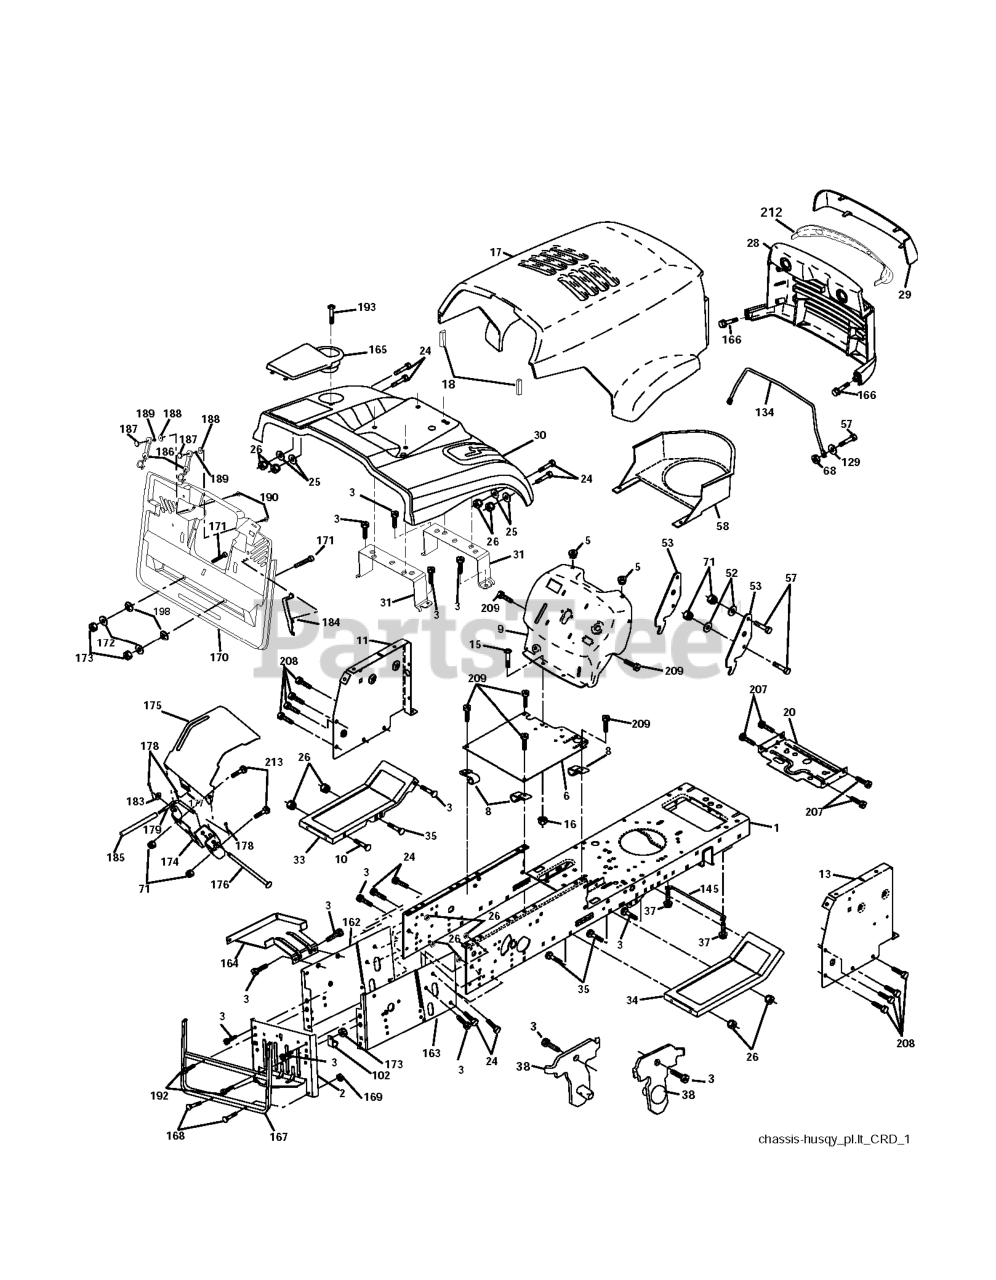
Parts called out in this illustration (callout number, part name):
1	CHASSIS STAMPING
3	SCREW 3/8-16X3/4
4	Washer 13/32 X 3/4 X 16 Ga.
5	BUMPER.RUBBER.HOOD
6	SADDLE FLAT
8	CLIP,INSULATOR
10	BOLT D
11	PANEL DASH LH
13	PANEL DASH
15	Screw, Machine, Truss Head 5/16-18 UNC x 3/4
16	NUT
17	HOOD
18	BUMPER HOOD T
20	PLATE MTG
25	WASHER
26	NUT
28	GRILL
29	LENS
30	FENDER
31	BRACKET SUPPORT FENDER
33	FOOT REST LH
34	FOOTREST RH
37	Screw 5/16-18 x 1/2 Hex, Self Tapping 5/16-18 x 1/2
38	BRACKET
53	BRACKET PNT PICK OFF LT/PL
57	BOLT
58	AIR DUCT P/L/LT
68	NUT
102	CLIP T
134	ROD SUPPORT HOOD LT/PL HUS.
145	ROD PIVOT CHASSIS/HOOD
165	COVER BATTERY
166	SCREW
167	SUPPORT.ASM.BACKPLATE
168	BOLT.ROUND.HEAD.SQUARE.NECK
169	NUT T
170	COVER BACKPLATE
172	WASHER
176	HINGE PIN
177	SPRING COVER LH
178	COTTER PIN
180	BOLT RB
181	LOCKNUT
183	WASHER
185	TUBE LEVER
186	LATCH ASSY
187	WELDNUT
189	LOCKWASHER #10
190	SCREW
192	SCREW LT
193	Screw Truss 1/4-20 x 3/4 Tap/R
207	SCREW, 5/16-18 X 1/2
208	SCREW 3/8-16X1/2
209	SCREW, 3/8-16X3/4
210	SCREW
